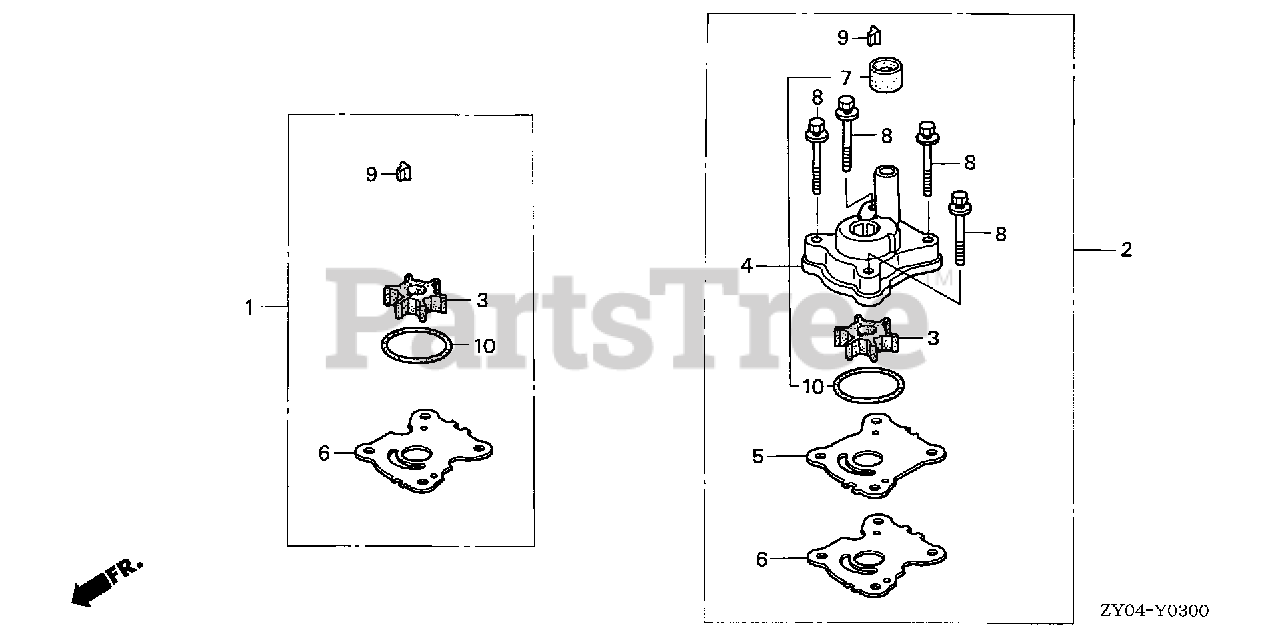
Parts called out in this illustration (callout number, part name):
1	PUMP KIT, IMPELLER
2	PUMP KIT, IMPELLER
3	IMPELLER, PUMP (UL)
4	HOUSING ASSY., IMPELLER
5	COVER, IMPELLER
6	GASKET, IMPELLER
7	RING, WATER TUBE SEAL
8	BOLT-WASHER (6X50)
9	KEY, WOODRUFF
10	O-RING (42.2X2.4)
